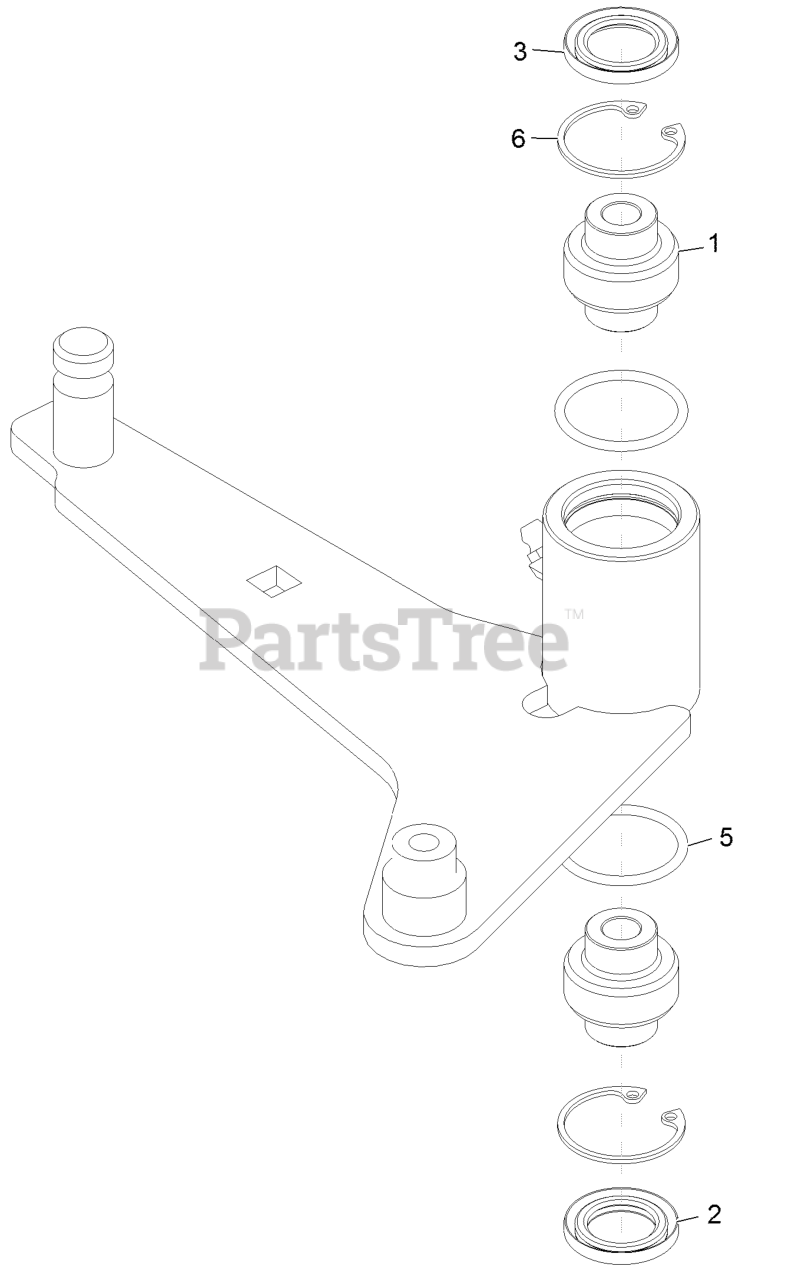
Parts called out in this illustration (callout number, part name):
1	BEARING-SPHERICAL
2	SEAL-LIP, DOUBLE
3	SEAL-LIP, SINGLE
6	RING-SNAP
